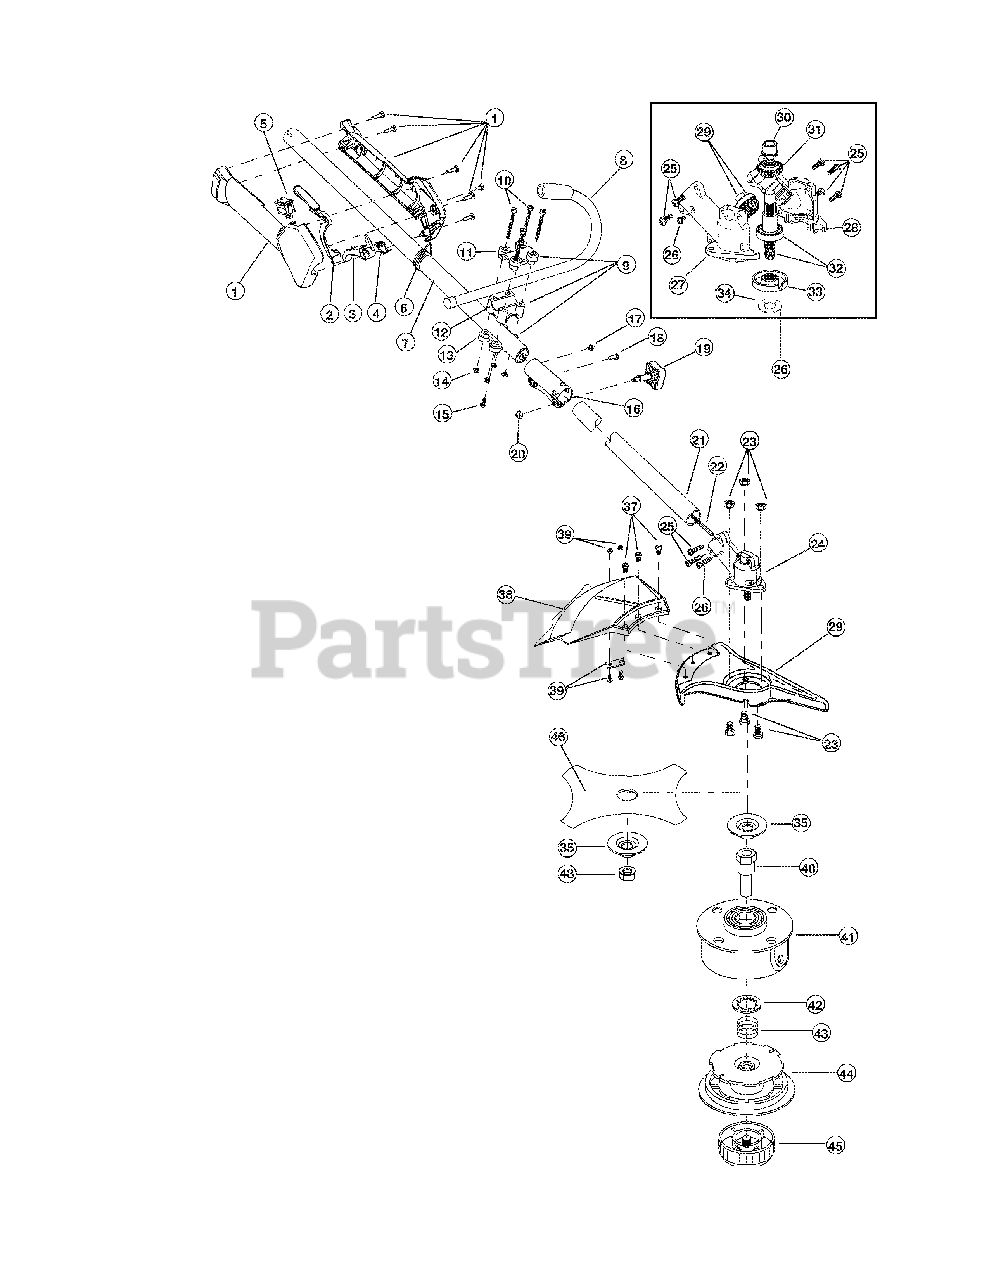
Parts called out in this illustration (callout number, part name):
1	Throttle Housing Assembly (includes 2-4)
2	Throttle Trigger Lock-Out
3	Throttle Trigger
4	Throttle Trigger Spring
6	Harness Clip
7	Upper Drive Shaft Housing Assembly
8	J-Handle Assembly
9	Handle Bracket Assembly (includes 10-15)
11	Upper Handle Clamp
12	Middle Handle Clamp
13	Lower Handle Clamp
15	Anti-Rotation Screw
16	Split Boom Coupler (includes 17-20)
19	Adjustment Knob
20	Knob Retaining Nut
21	Lower Drive Shaft Housing Assembly
22	Lower Flexible Drive Shaft
23	Shield Mount Screw Assembly
24	2 piece Gearbox Assembly (includes 25-35)
25	Gearbox Mounting Hardware
26	Anti-Rotation Screw
27	Right Housing
28	Left Housing
29	Pinion Gear Assembly
30	Output Shaft Bushing
31	Output Shaft Gear
32	Output Shaft Assembly (includes 30 & 31)
33	Blade Driver
35	Retaining Washer
36	Blade Shield/Shield Mount
37	Shield Mounting Screw
38	Shield Assembly (includes 39)
39	Blade Assembly
40	Spool Shaft
41	Outer Spool Assembly (includes 42)
42	Retainer
45	Bump Head Knob Assembly
46	4-Tooth Blade
48	Nut
